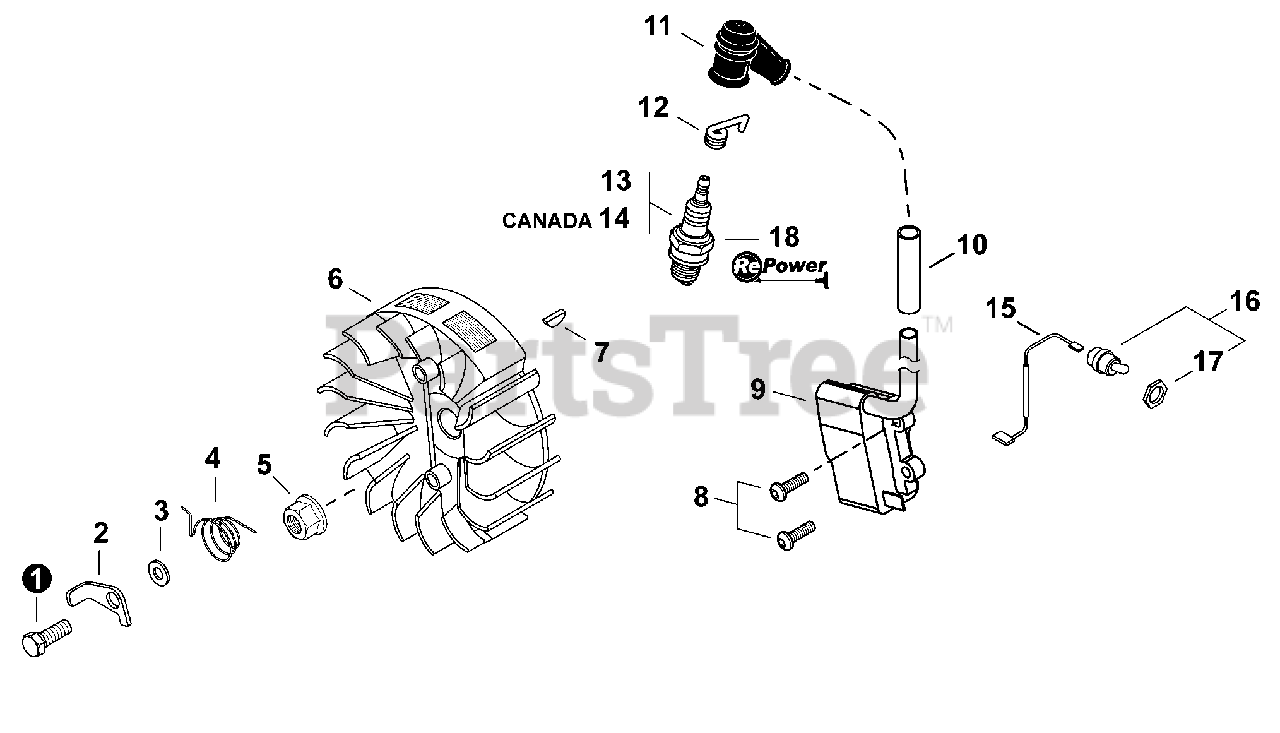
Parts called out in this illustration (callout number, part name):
3	WASHER 6
4	SPRING, TORSION
5	NUT M8×1.0
6	FLYWHEEL
7	KEY, WOODRUFF 3×10
8	BOLT, ADHESIVE M4×20
9	COIL ASSY, IGNITION
10	TUBE, INSULATOR
11	CAP, SPARK PLUG
12	TERMINAL, SPARK PLUG
13	SPARK PLUG - BPM8Y
14	SPARK PLUG - BPMR8Y
15	LEAD - IGNITION
16	SWITCH ASSY, ON-OFF
18	TUNE-UP KIT - REPOWER
